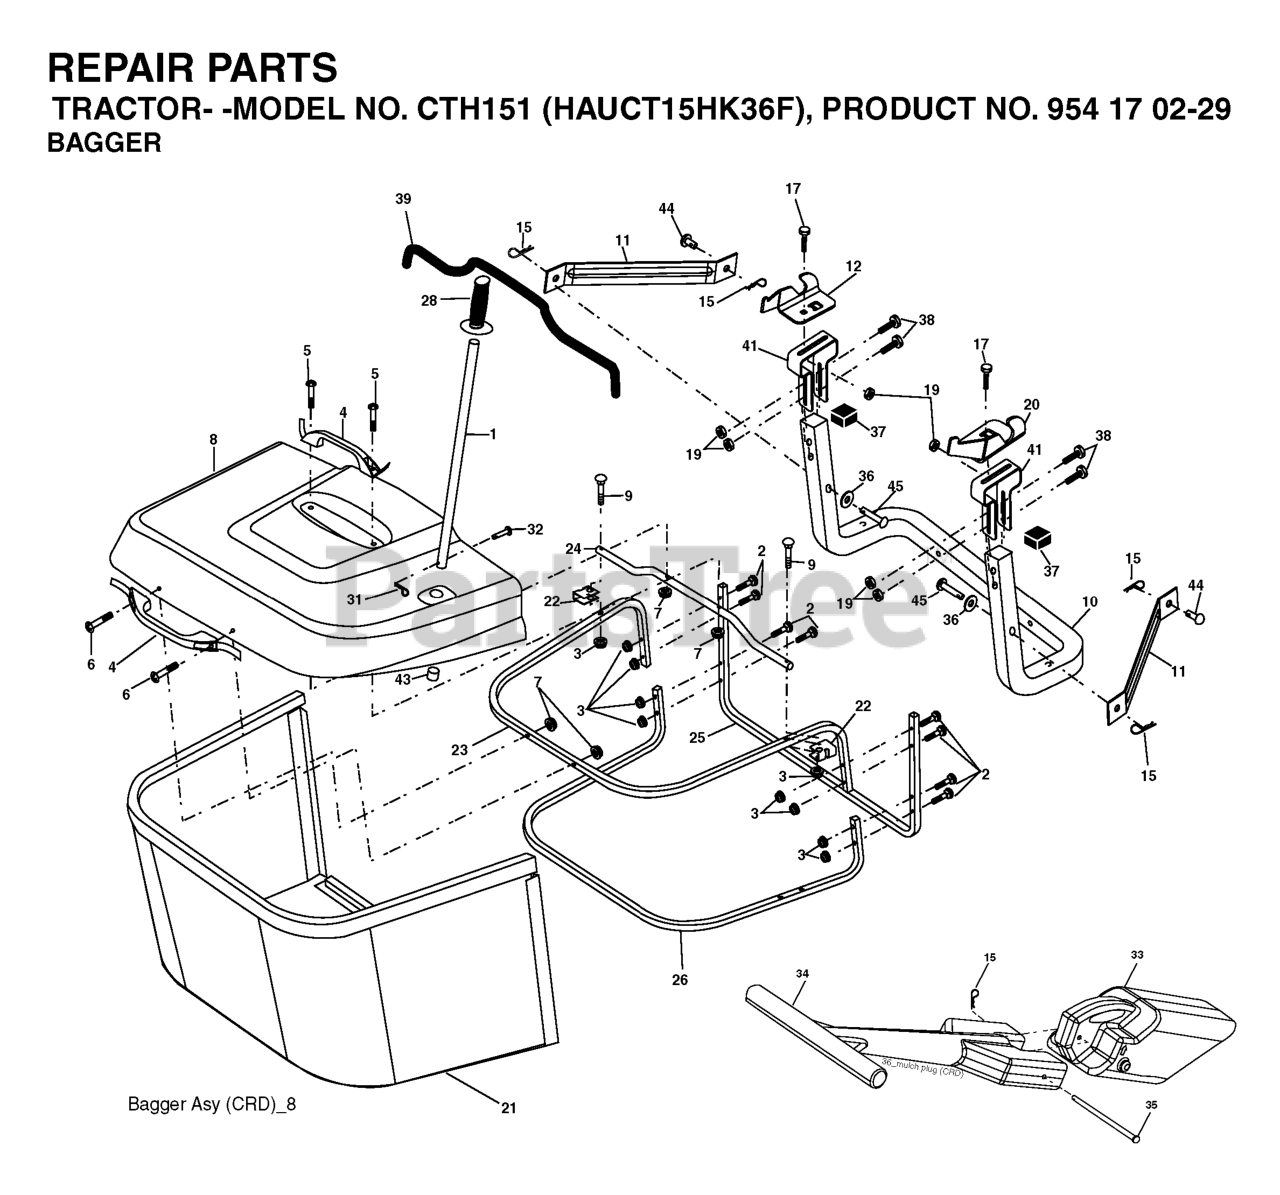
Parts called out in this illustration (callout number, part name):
1	TUBE HANDLE
2	Bolt Carriage 1/4-20 x 2.0 Gr.5
3	NUT T
4	HANDLE.BAGGER.W/LVRS.BLK.CRD
5	SCREW.PAN.HEAD
6	REPL BY 532 75 00-29
8	COVER.PNT.BGR.CRD.WSLOTS.MS668
9	Bolt Carriage 1/4-20 x 2.25d x Gr.5
10	TUBE
11	BRACKET.SUPPORT.UPPER.BAG.CRD
12	BRKT PIVOT
15	RETAINER-SPRNG RB
17	RP BOLT 5/16-18 X3/4 ZN/YEL GR
19	NUT LOCK HEX FLANGE 5/16-18
20	BRKT.PIVOT.RH.CRD
21	GRASS BAG
22	BRKT.SIDE.BAG.CRD
23	TUBE.UPPER.BAG.CRD
24	TUBE.PIVOT.BAG.CRD.BLACK
26	TUBE.LOWER.BAG.CRD
28	GRIP.HANDLE.BLACK
31	RETAINER CLIP
32	RIVET,DRILLED
33	PLUG.MULCHER.92 CRD
34	HANDLE.MULCHER.92.CRD (2 2)
36	WASHER
37	Plug Support Bagger CRD
38	BOLT.5/16-18X2.5
39	SEAL.TRIM.37'
41	BRKT.VERT.ADJ.BAGGER.CRD
43	PLUG, TUBING END
